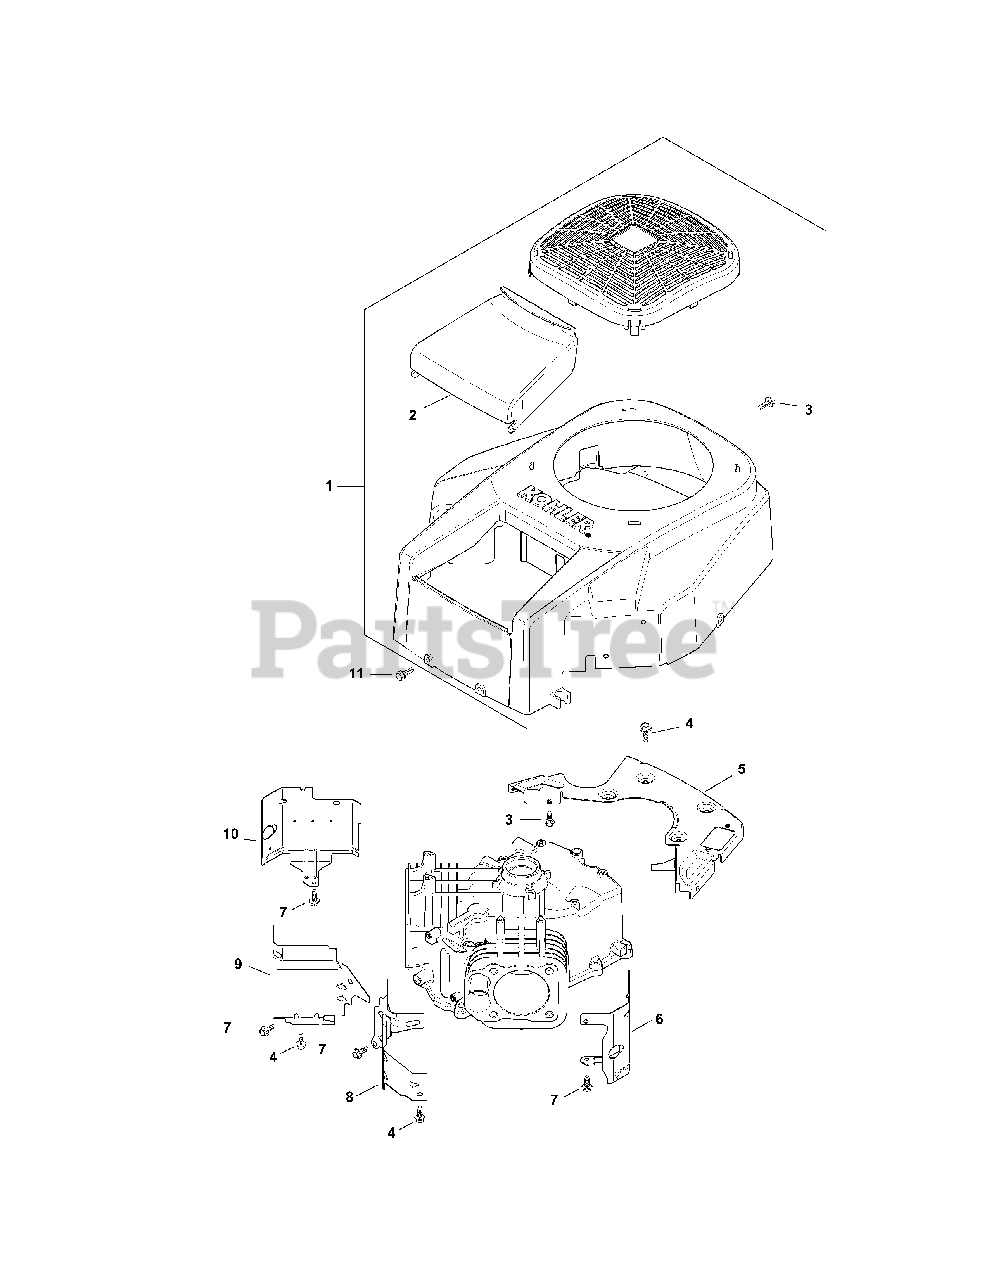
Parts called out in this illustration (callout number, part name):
1	Kit, Blower Housing-Fixed Guard
2	Cover, Air Cleaner (Black)
3	Screw, FLG THD FRM M5 x .8 x 10
4	Screw, FLG THD FRM M5 x .8 x 16
5	Kit, Backing Plate
6	Baffle, Cyl Barrel-#2 Side
7	Screw, FLG THD FRM M6 x 1.0 x 16
8	Baffle, Valley #2 Side
9	Baffle, Valley #1 Side
10	Baffle, CYL Barrel - #1 Side
11	Screw, Tap M6 x 1.7 x 18
